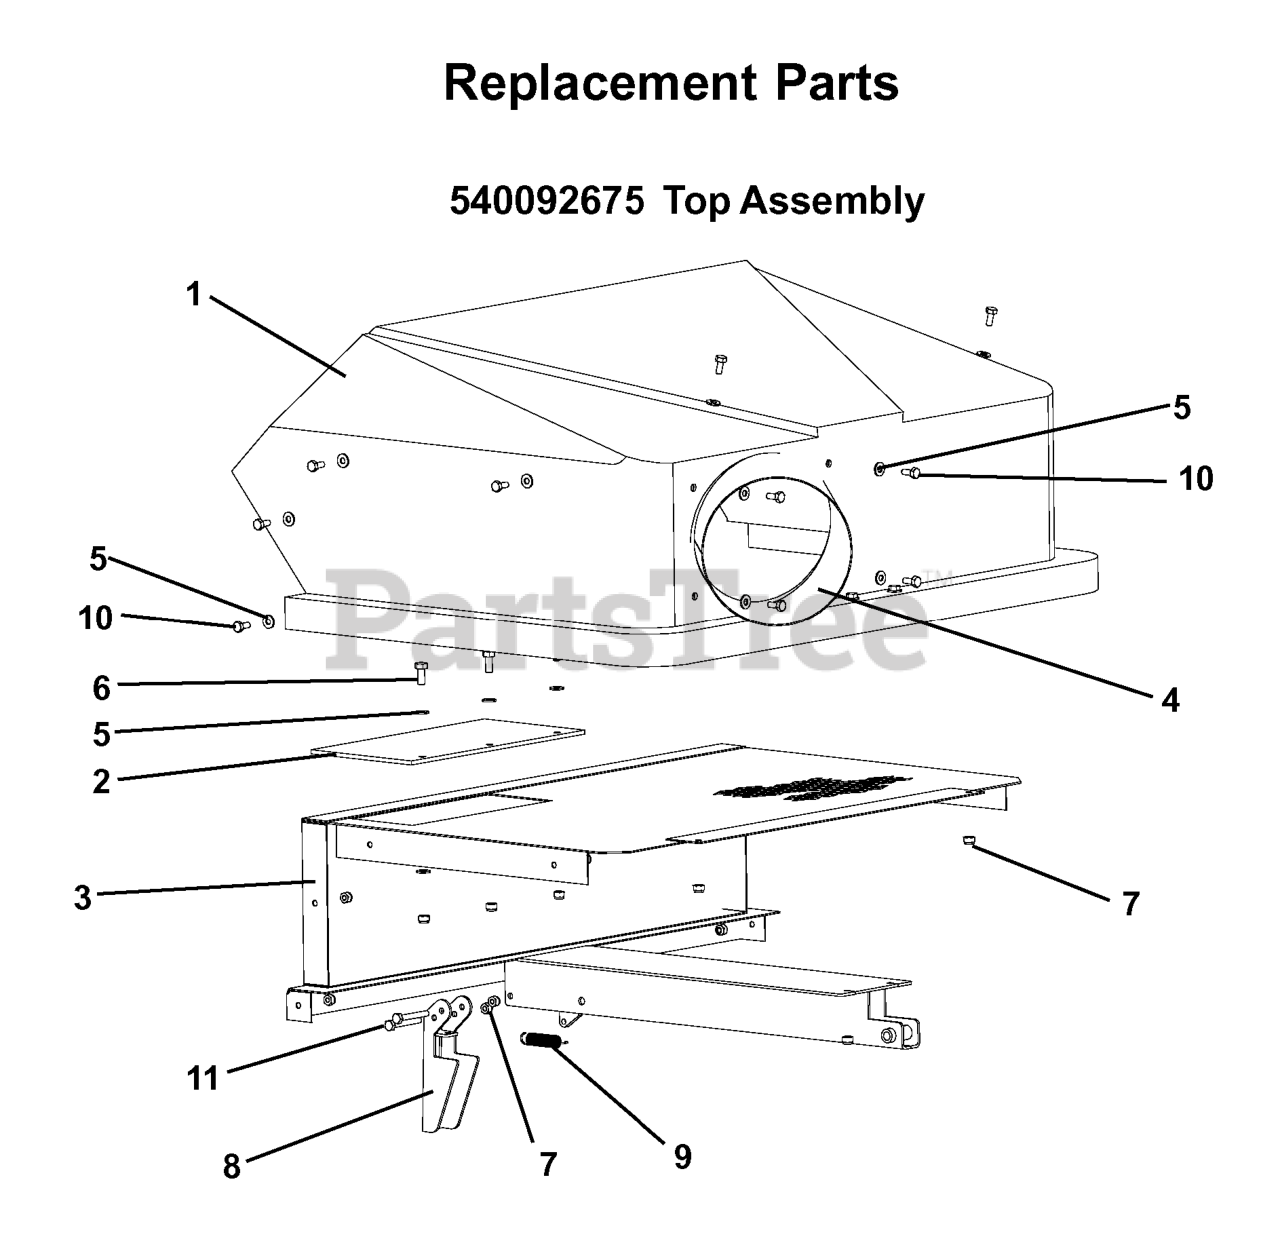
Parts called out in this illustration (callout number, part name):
1	MOLDED TOP
2	RUBBER FLAP
3	TOP INSERT
4	BLOWER HOUSING INLET
5	Washer, Flat, 1/4"
6	Bolt, Hex, 1/4"-20 x 3/4", Gd. 5
7	Nut, Hex, Nylon Lock, 1/4"-20
8	LATCH - CZ9
9	SPRING, TRIP LEVER
10	Bolt, Hex, 1/4"-20 x 5/8"
11	BOLT 1/4-20 X 2"
